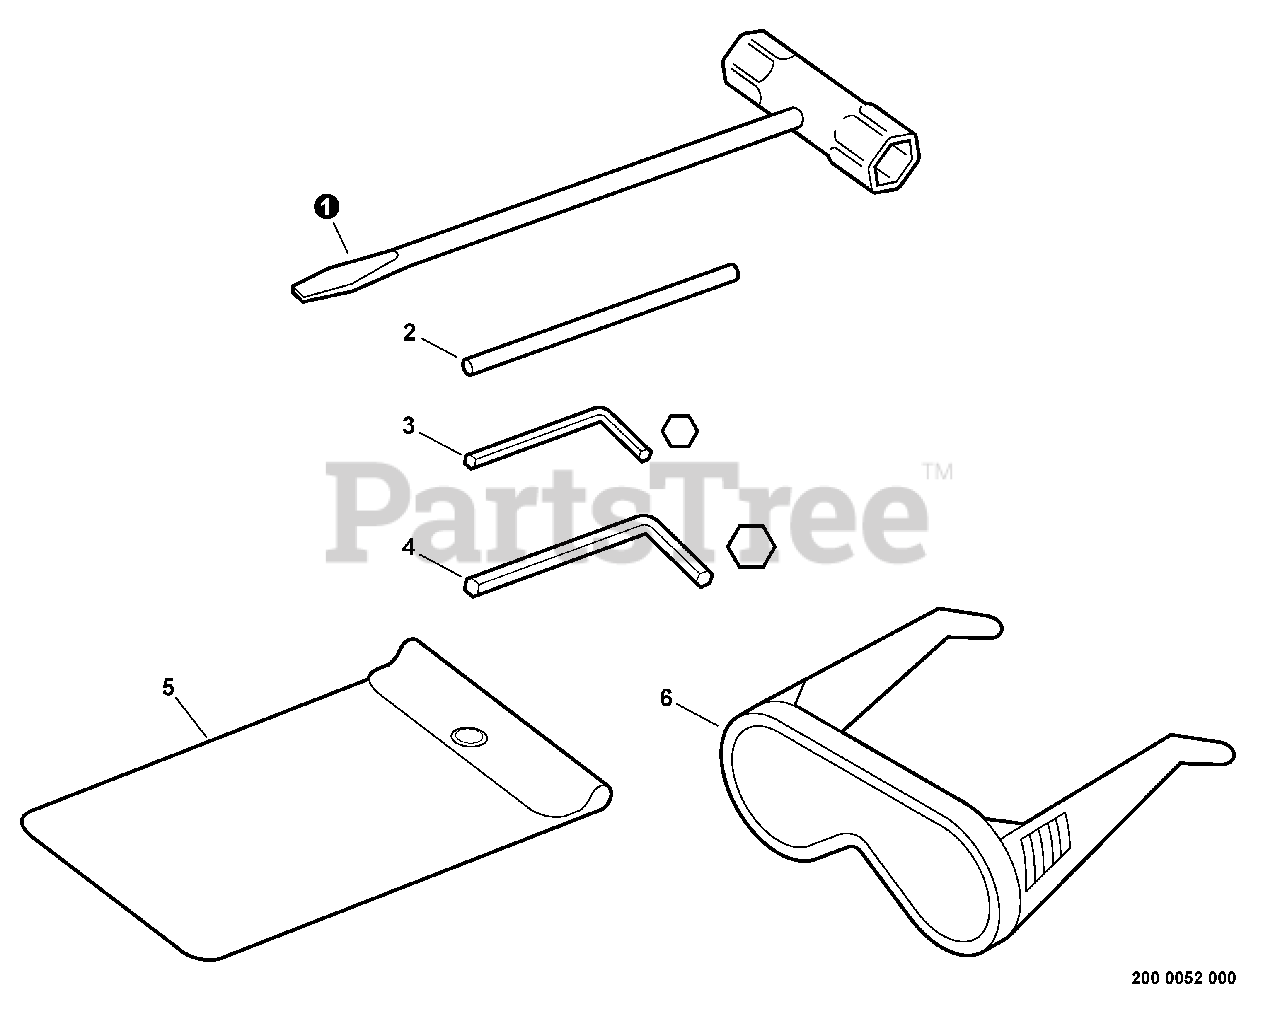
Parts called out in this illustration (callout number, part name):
1	T-WRENCH - 17X19mm
2	ROD, LOCKING - 5X120mm
3	HEX KEY - 3mm
4	HEX KEY - 4mm
5	BAG, TOOL
6	GOGGLES
